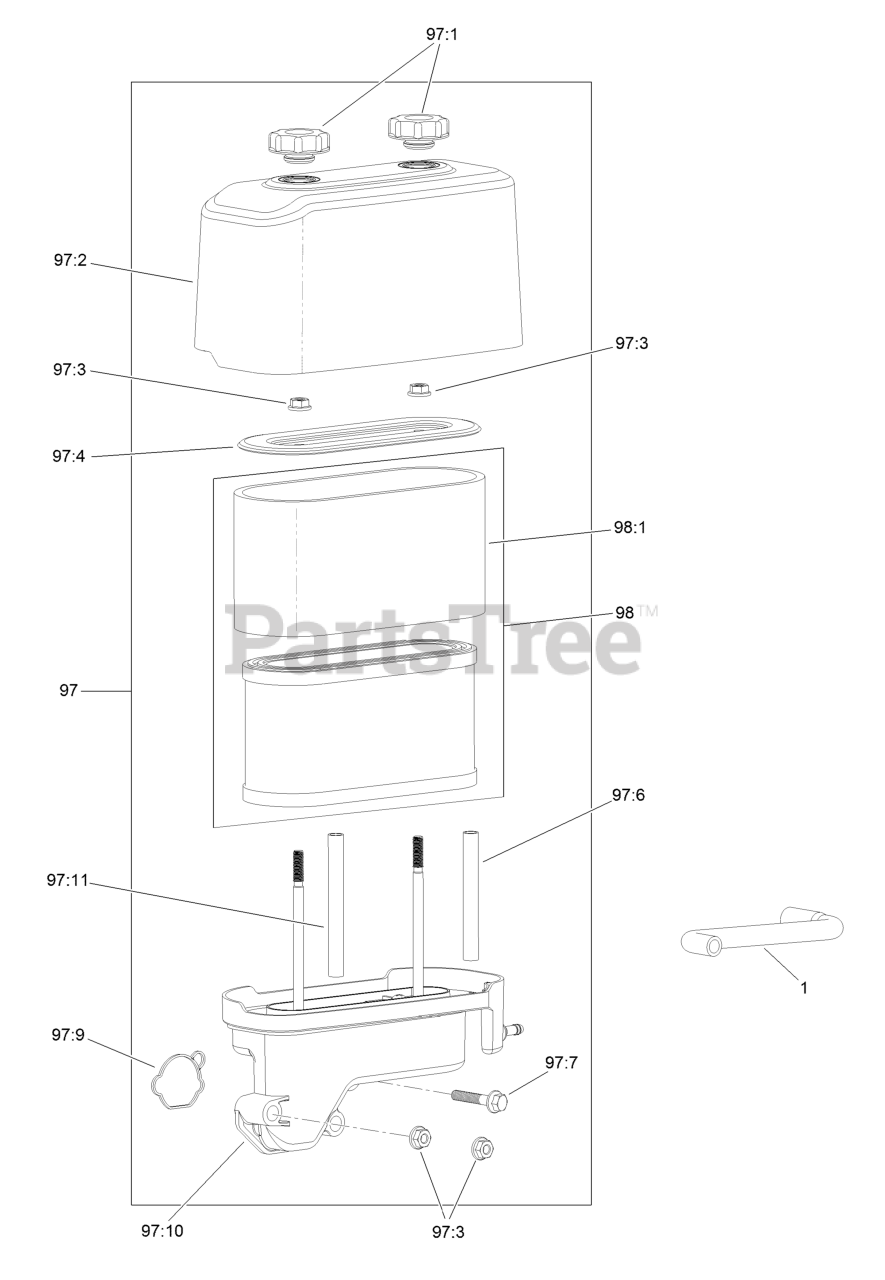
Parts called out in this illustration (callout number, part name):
1	TUBE-BREATHER
97:1	NUT-SPEED
97:2	COVER-FILTER, AIR
97:3	NUT-FLANGE
97:6	SPACER-FILTER, AIR
97:7	SCREW-HHF
97:9	GASKET-CARBURETOR
97:11	SPACER-FILTER, AIR
98:1	PREFILTER
